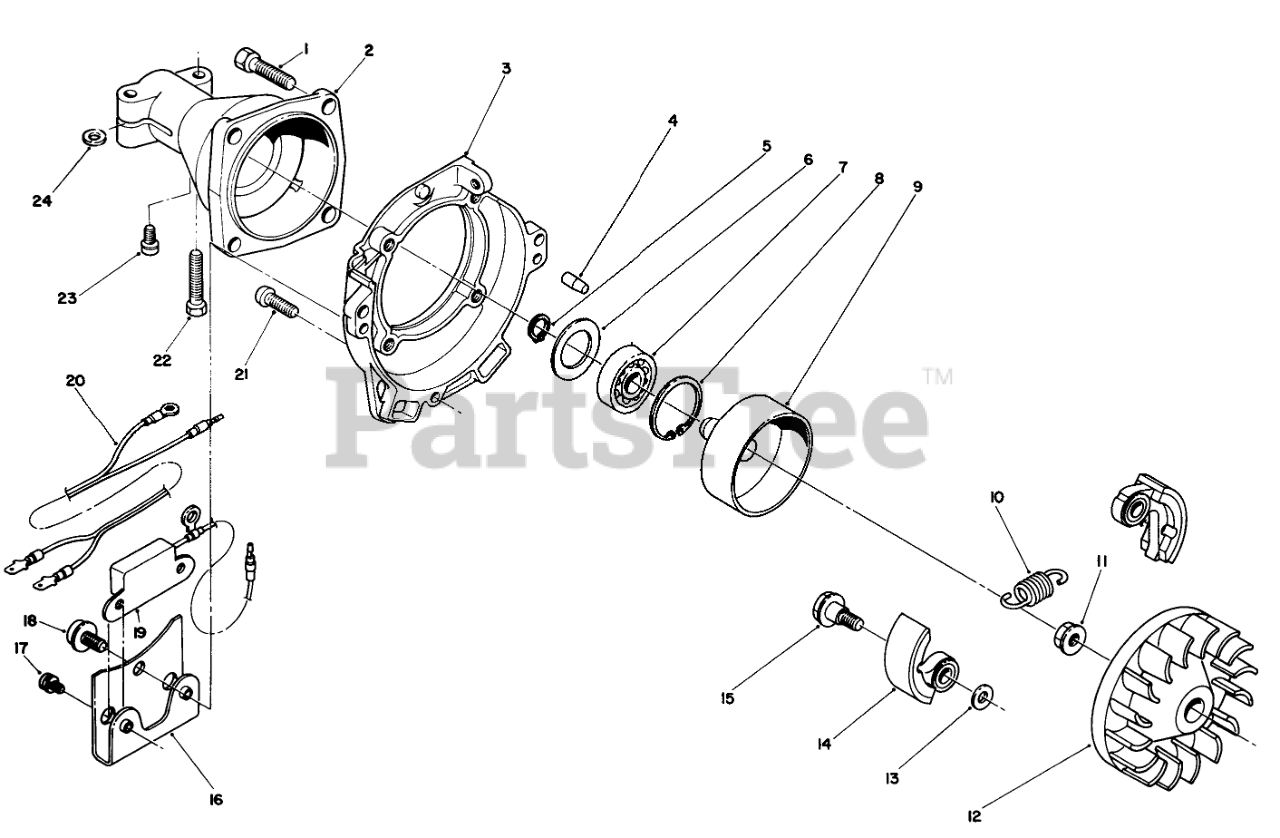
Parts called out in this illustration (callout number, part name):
1	Bolt/Washer
2	CLUTCH CASE
3	Case, Fan
5	SNAP RING
6	Washer
7	BALL BEARING
8	SNAP RING
9	CLUTCH DRUM
10	Spring
13	WASHER
14	SHOE, CLUTCH
15	CLUTCH BOLT
16	Bracket-Unit
17	SCREW W/ WASHER
18	SCREW & WASHER
19	TRANSISTOR
20	WIRE,LEAD
21	BOLT & WASHER
22	BOLT-WASHER/ENG
23	Screw/Washer
24	WASHER
